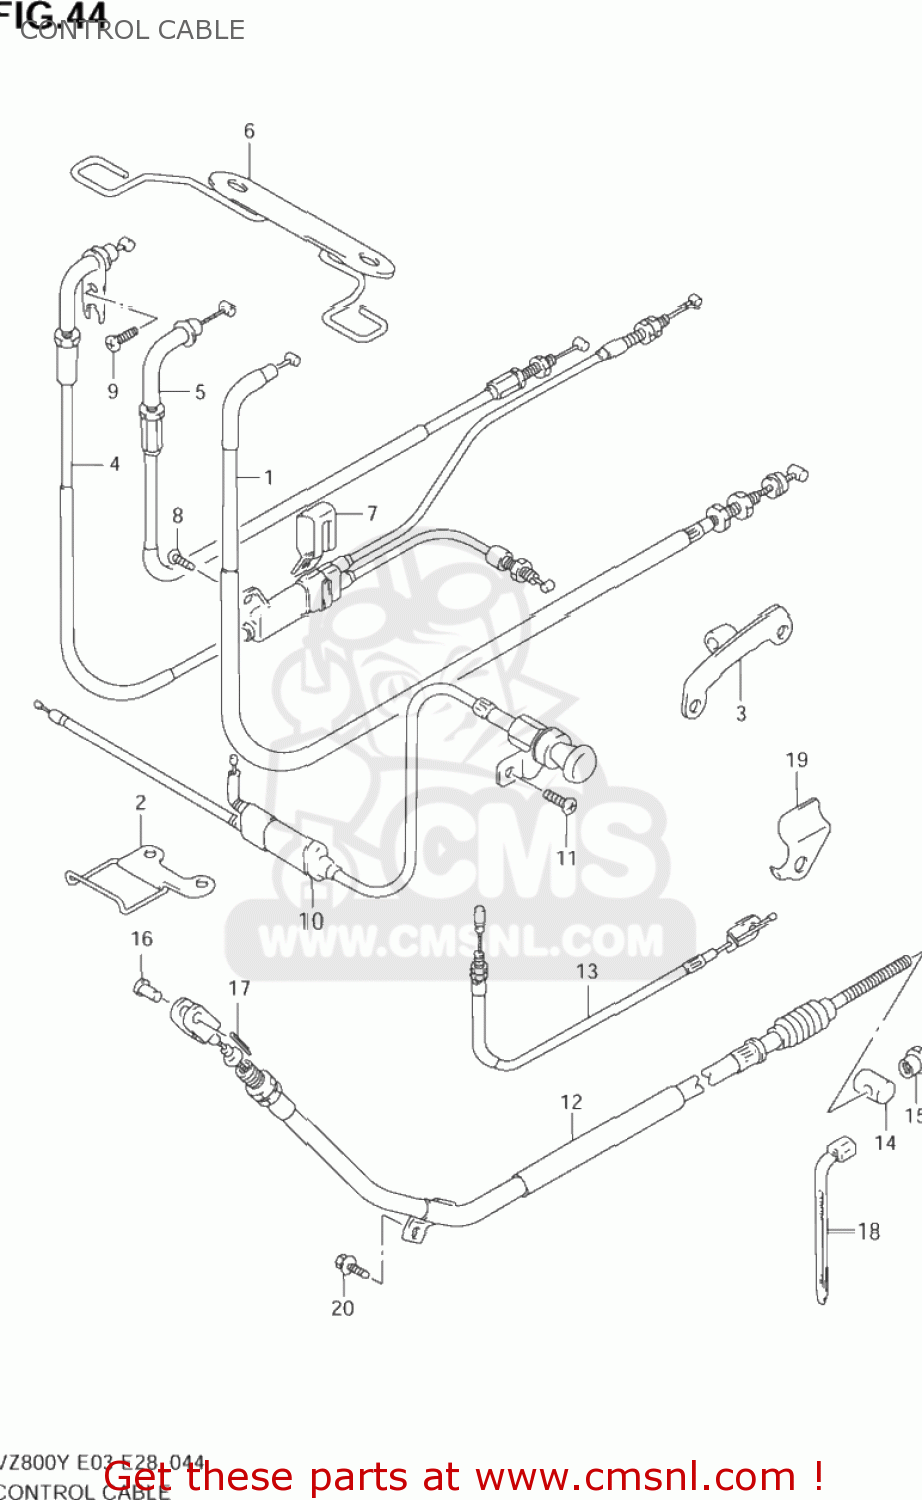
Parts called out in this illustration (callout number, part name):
1	CABLE ASSY,CLUTCH
2	GUIDE,CLUTCH CABLE
3	STOPPER,CLUTCH CABLE
4	CABLE ASSEMBLY,THROTTLE
5	CABLE ASSEMBLY,THROTTLE NO
6	GUIDE,CABLE
7	CLAMP,THROTTLE CABLE CONNECTOR
8	SCREW
9	SCREW
10	CABLE ASSY,STARTER
11	SCREW(6X10)
12	CABLE,RR BRAKE
13	CABLE,STOP LAMP SWITCH
14	PIN(13X18)
15	NUT
16	PIN(L:17.5)
17	PIN
18	CLAMP(L:125)
19	CLAMP,RR BRAKE CABLE
20	BOLT
